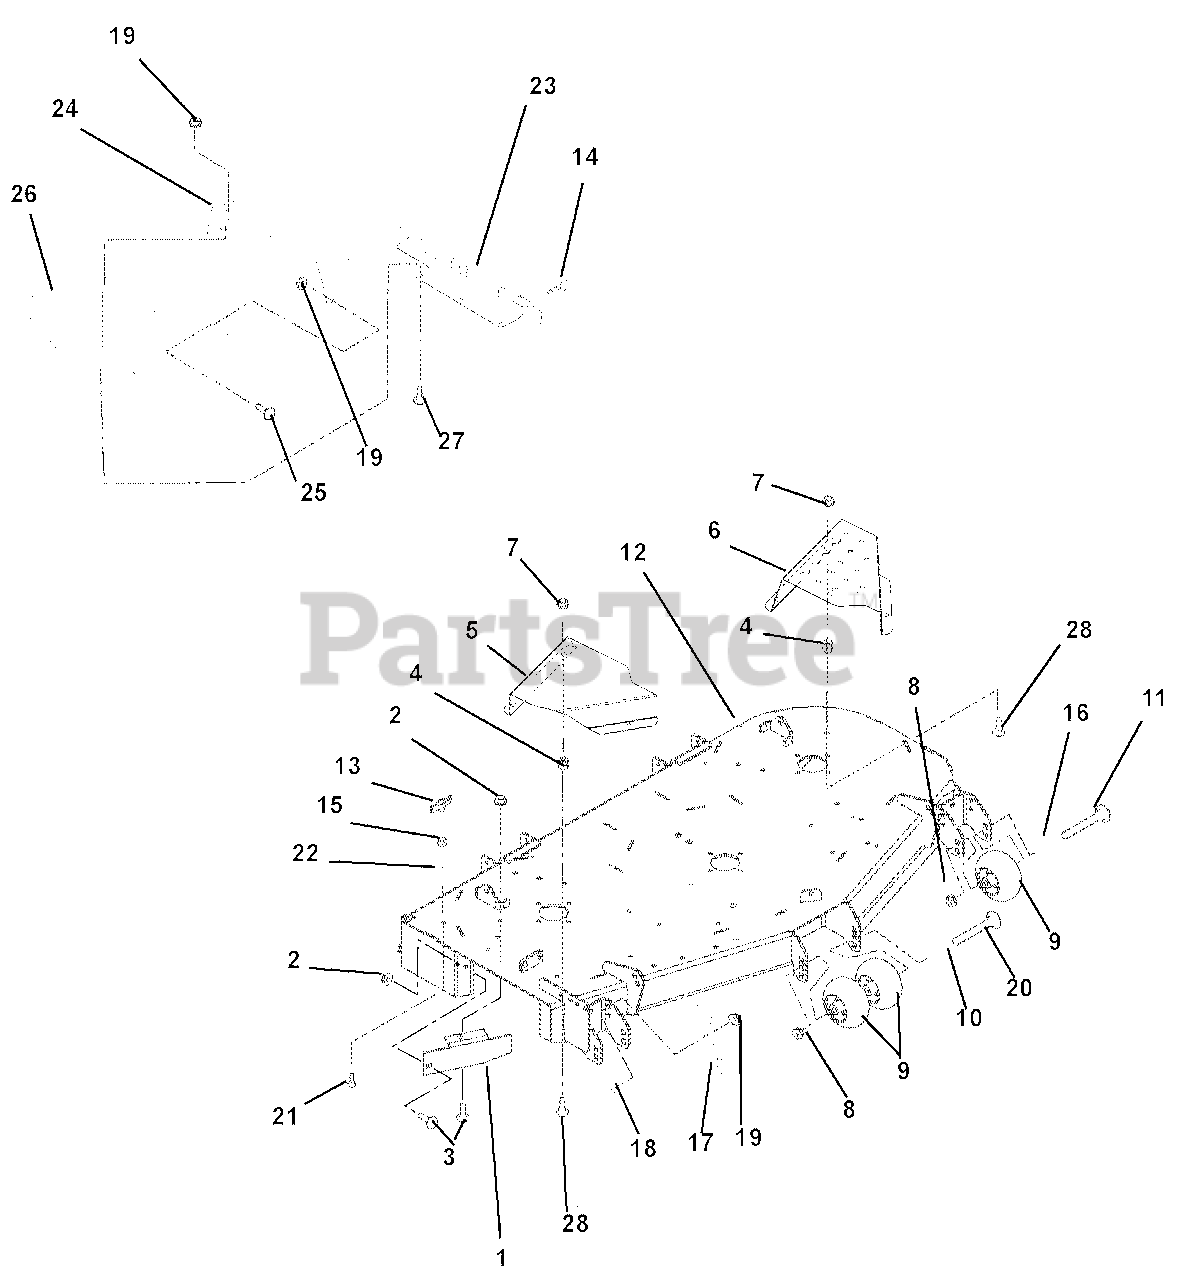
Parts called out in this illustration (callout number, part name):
1	60" DISCHARGE BAFFLE - RED
2	@NUT-LK-NYL-FLG .31-18 YWZC
3	@BLT-RDHDSQNK .31-18X1.00 G5YZ
4	NUT-HEAVY HEX .38-16 YWZC
5	GUARD,RH DECK BELT,60-66
6	GUARD,LH DECK BELT,60
7	@NUT-SPNLK-FLG .375-16 YWZC
8	@NUT-LK-NYL-FLG .50-13 YWZC
9	ANTI-SCALP WHEEL - 5X3 CTR
10	SPACER, .510X.625X6.50
11	BLT-RDHDSQNK .50-13X5.00 GR5YZ
12	PM260 SIDE DISCH DECK WMT -RED
13	KNOB-CLAMPING, .312-18 NYLOC
14	PULL PIN,.50-13THDX.310 PLNGR
15	@NUT-LK-CTR .31-18 YWZC
16	SPACER, .510X.625X3.35
17	CHUTE STORAGE BRACKET - RED
18	@BLT-HEX .38-16X1.00 GR5 YWZC
19	@NUT-LK-NYL-FLG .38-16 YWZC
20	@BLT-RDHDSQNK .50-13X8.50 G5YZ
21	@BLT-RDHDSQNK .31-18X1.50 G5YZ
22	BUMPER,RECESSED1.50X.63 W/.31
23	WMT, 52"-60" DISCH CHUTE MTG
24	RUBBER DISCH CHUTE SUPPORT-RED
25	@BLT-RDHDSQNK .38-16X1.00 G5YZ
26	CHUTE, RUBBER DISCHARGE
27	@BLT-RDHDSQNK .38-16X1.25 G5YZ
28	@BLT-HEX .38-16X1.25 GR5 YWZC
